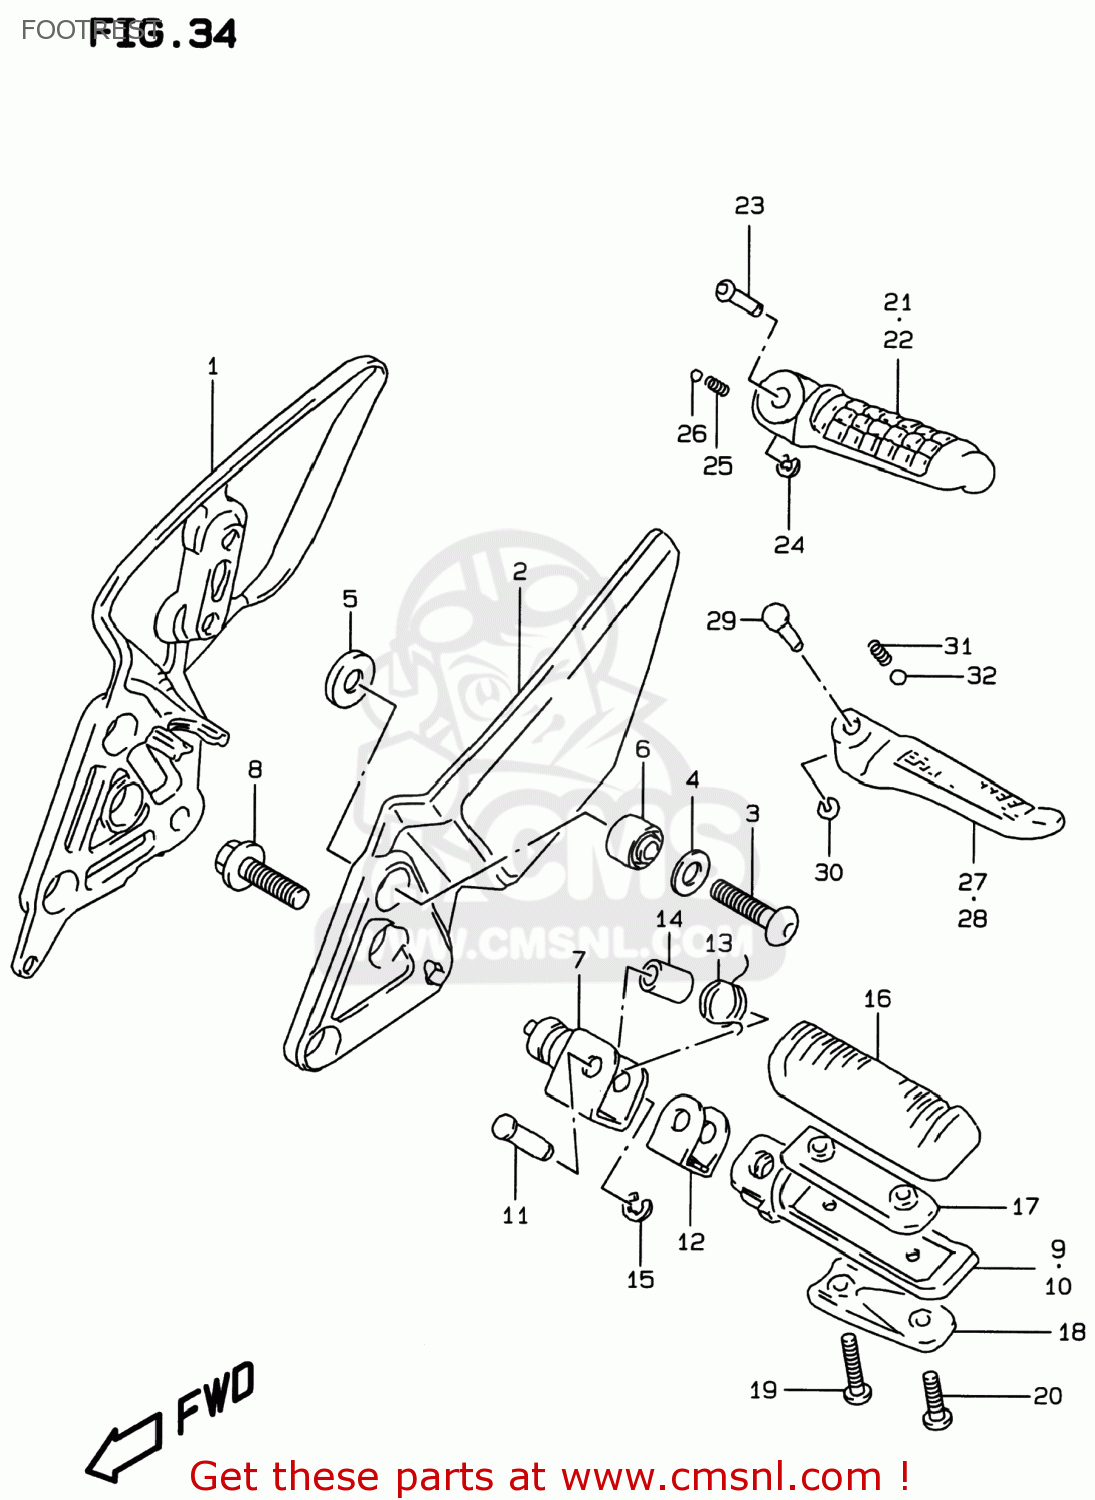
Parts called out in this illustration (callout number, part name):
1	BRACKET,FRONT FOOTREST
2	BRACKET,FRONT FOOTREST
3	BOLT(8X28)
4	WASHER (8.5X24X1.6)
5	WASHER(12.6X24X1.9)
6	BUSH(12X20X16)
7	HOLDER,FOOTREST
8	BOLT(10X28)
9	BAR,FOOTREST,R
10	BAR,FOOTREST,L
11	PIN(8X33.2)
12	CUSHION,FR FOOTREST
13	SPRING
14	SPACER(8.1X12X22)
15	E.RING
16	RUBBER,FOOTREST
17	BAR,FR FOOTREST NO.2
18	BALANCER,FR FOOTREST LWR
19	SCREW
20	SCREW
21	BAR,PILLION FOOTREST,R
22	BAR,PILLION FOOTREST,L
23	PIN
24	E.RING
25	SPRING
26	BALL
27	BAR,PILLION FOOTREST,RIGHT
28	BAR,PILLION FOOTREST,LEFT
29	PIN
30	E-RING
31	SPRING
32	BALL
